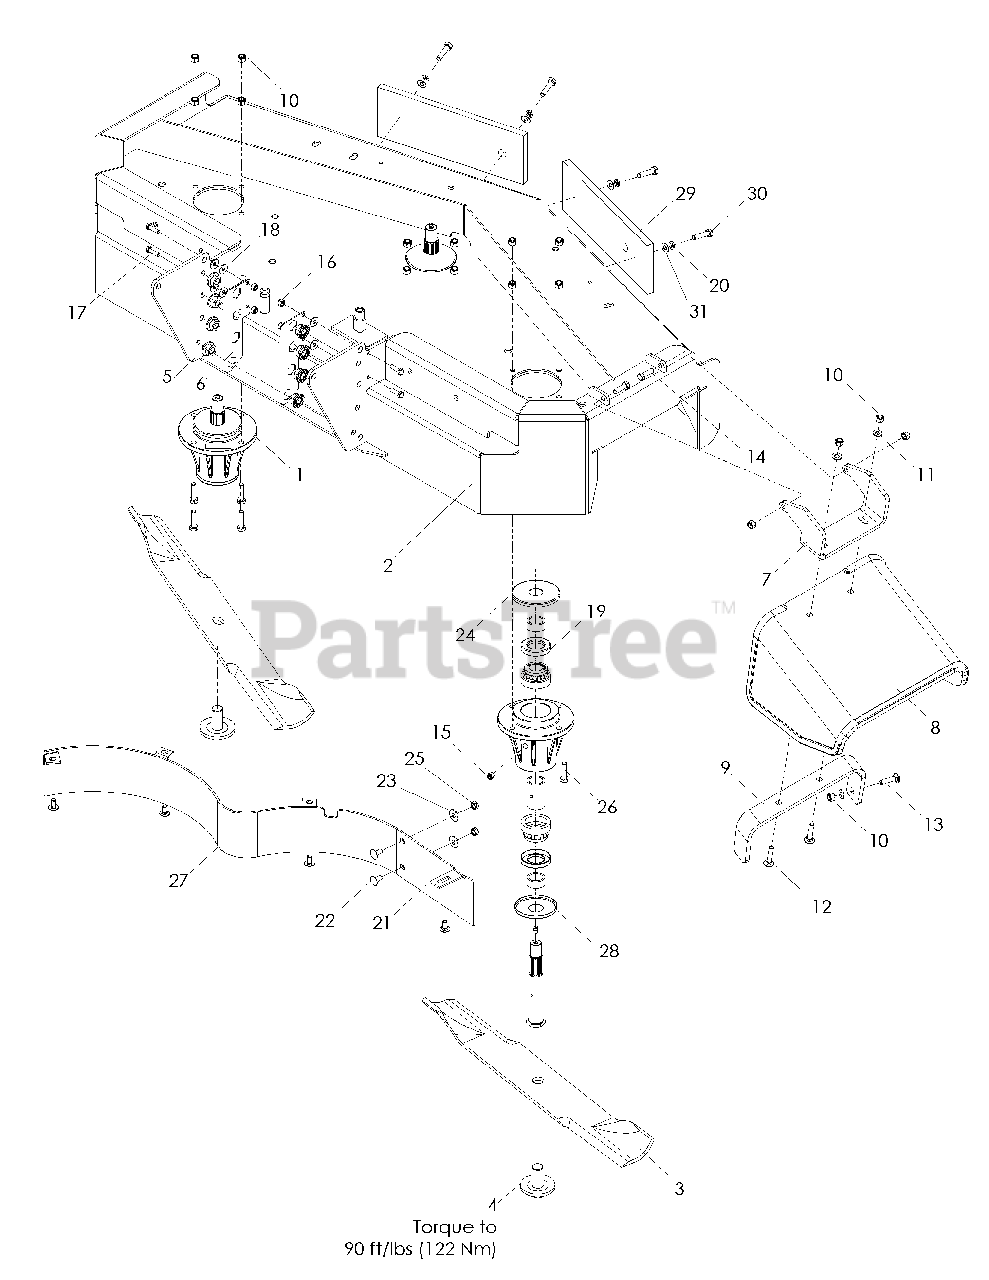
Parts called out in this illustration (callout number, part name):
1	SPINDLE ASSEM
2	DECK W DECALS, 48"
4	BOLT, BLADE
5	NUT, FLANGE, 1/2-13
6	NUT, PLATE
7	HINGE, CHUTE
8	RUBBER CHUTE
9	REINFORCEMENT, BRKT
10	NUT 5/16-18 HEX NYLOC
11	WASHER 5/16 SAE FLAT
12	RHSNB 5/16-18 x 1 1/2
13	RHSNB 5/16-18 x 1 1/4
14	HCS 5/16-18 x 1
16	NUT 1/4-20 HEX NYLOC
17	HCS 1/4-20 x 7/8
18	WASHER 1/4 FLAT
19	SEAL, SHAFT
20	WASHER 1/2 SLW
21	CENTER BAFFLE
22	RHSNB 5/16-18 x 5/8
23	WASHER 5/16 STD FLT
24	DUST CAP, TOP
25	NUT 5/16-18 HEX CTRLK
26	HCS 5/16-18 x 1 1/4
27	MAIN BAFFLE
28	DUST CAP, BOTTOM
29	WEIGHT, COUNTER
30	HCS 1/2-13 x 1 1/2
31	WASHER 1/2 SAE FLAT
